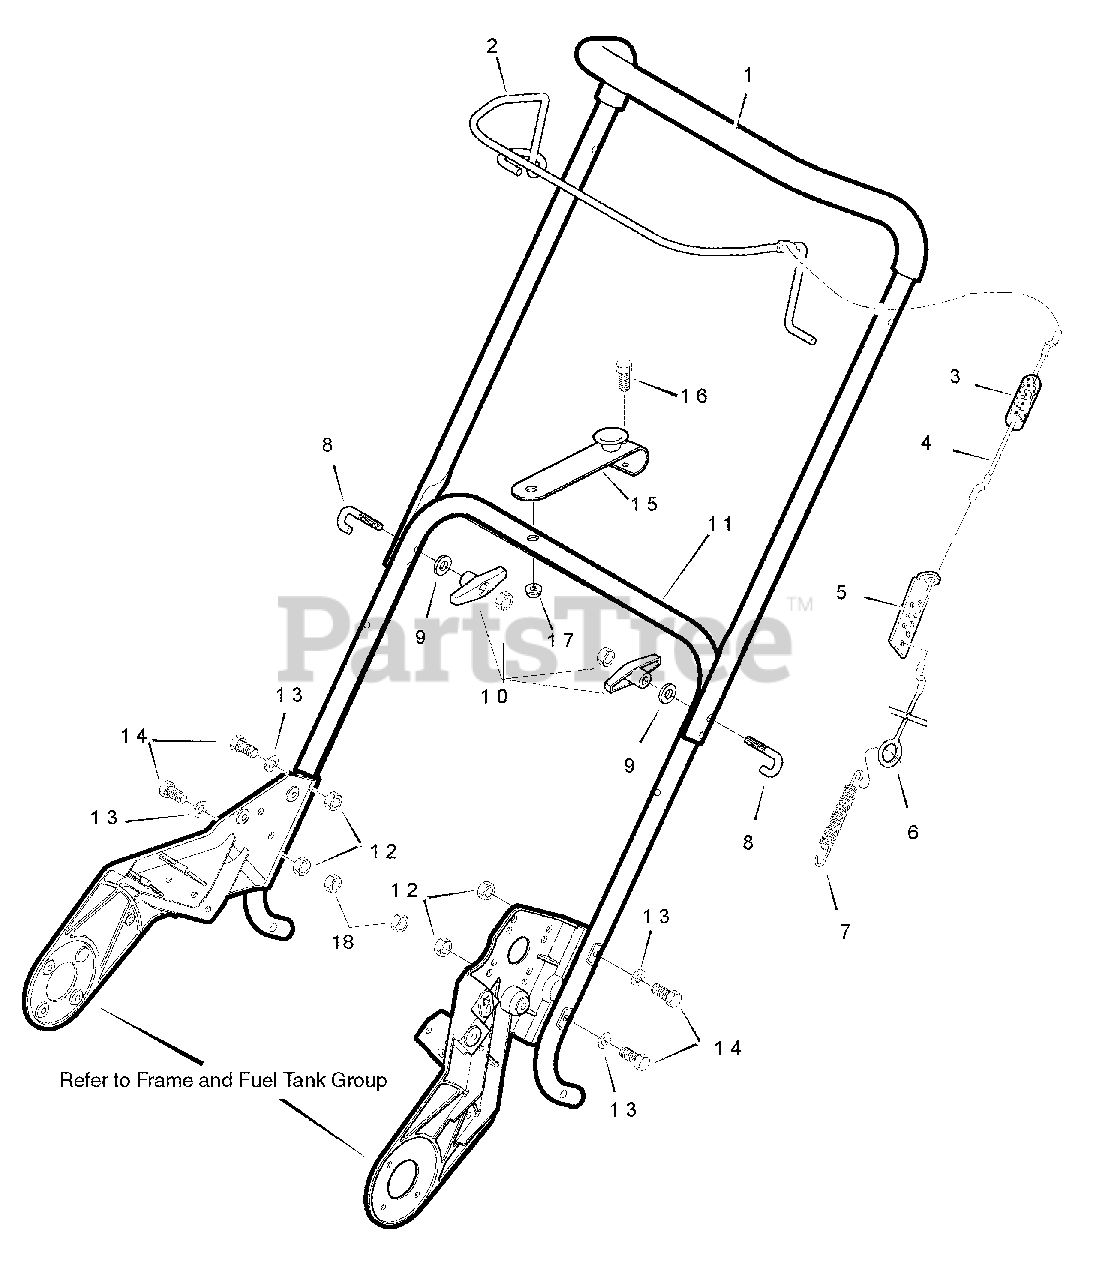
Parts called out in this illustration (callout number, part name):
1	HANDLE & GRIP ASSEMBLY
2	CONTROL, Bail
3	BOOT, Clutch Spring
4	CABLE, Upper Control
5	BRACKET, Control Adjust
6	CABLE, Lower Control
7	SPRING, Extension 3/4 O.D. x .069
8	U-BOLT, 5/16-18
9	WASHER, Form 11/32 ID 1.0
10	WING KNOB, (includes 5/16-18 hex nut #722399)
11	HANDLE, Lower
12	NUT, 1/4-20 Regular Hex Control Lock
13	WASHER FLAT 9/32 x 5/8 x .065
14	SCREW, 1/4-20 x 1.25
15	BRACKET, Chute Handle Assembly
16	BOLT, 1/4-20 x 1.50 Hex Head
17	NUT, 1/4-20 Hex Head Nylock Blk
18	Nut, 5/16-18 Hex Center Lock
